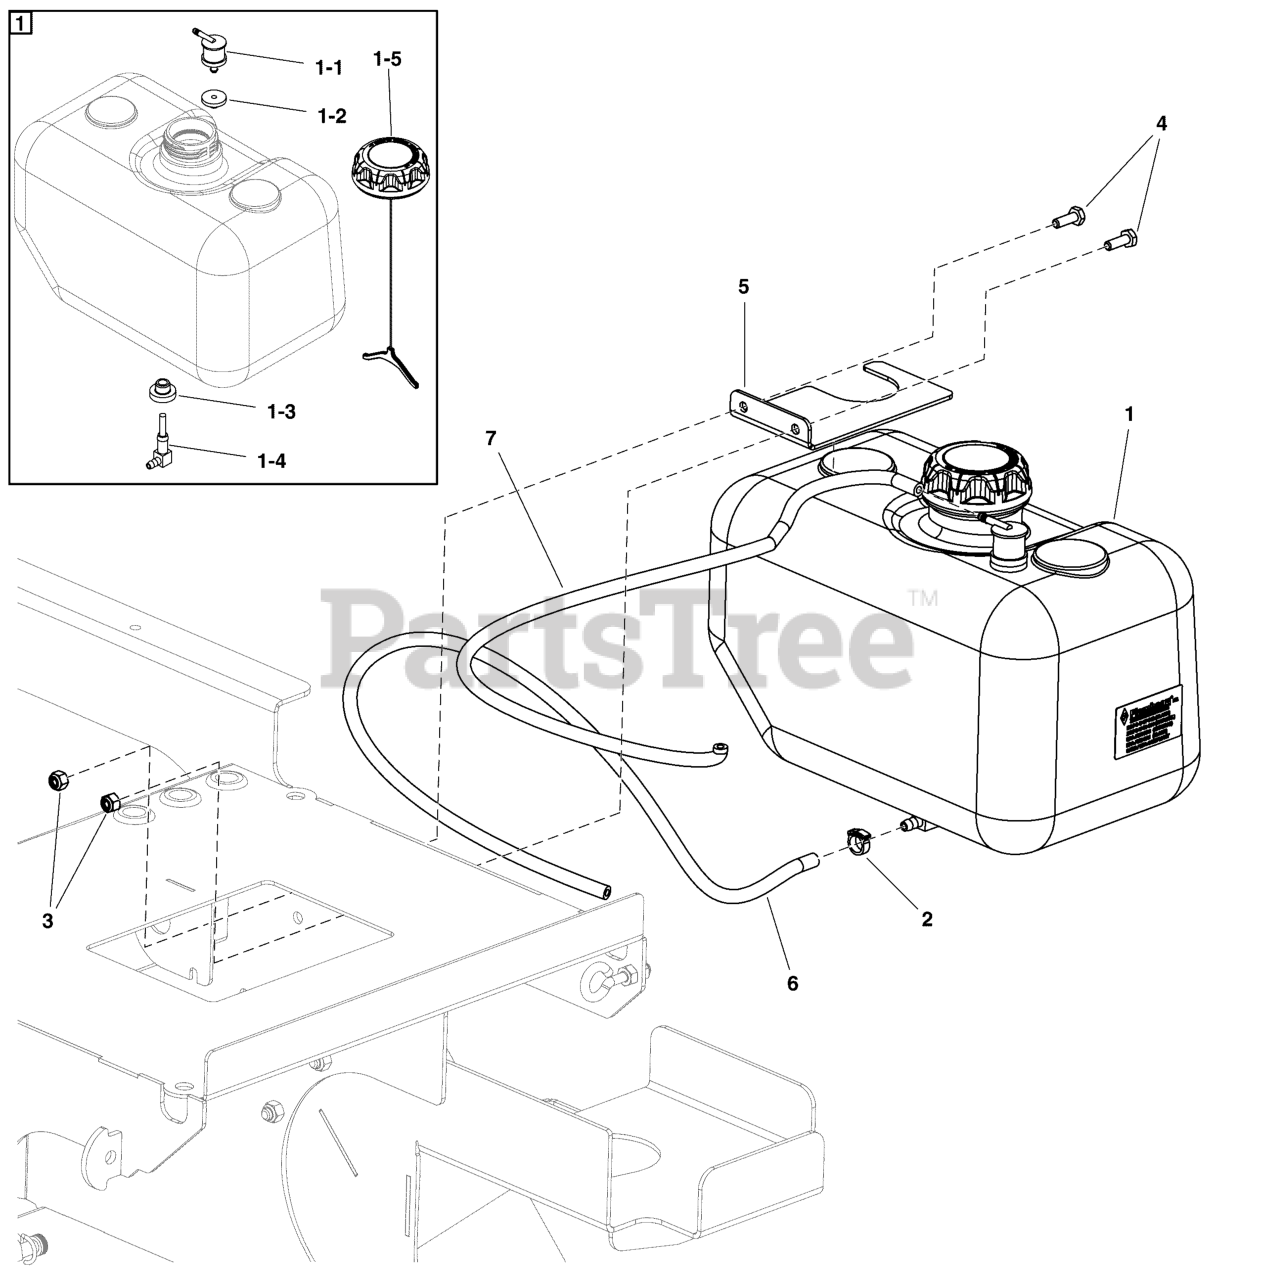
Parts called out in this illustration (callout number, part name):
1	TANK, FUEL 2.5 GAL EPA/CARB
1-1	VALVE, SLOSH (C0155)
1-2	GROMMET, SLOSH VALVE (C0156)
1-3	GROMMET, VALVE, FUEL TANK (B0142)
1-4	FITTING, FUEL TANK (B0115)
1-5	CAP, FUEL, EPA (C0139)
2	CLAMP, 3/16 FUEL LINE
3	NUT-HEX-NYLK, .250"-20 SS188
4	SCR-CAP, HEX .250"-20 X .750" SS188
5	BRACKET, HOLD DOWN, FUEL TANK
6	LINE, FUEL 3/16" ID X 15.0"
7	HOSE, FUEL VENT EPA 3/16" ID
